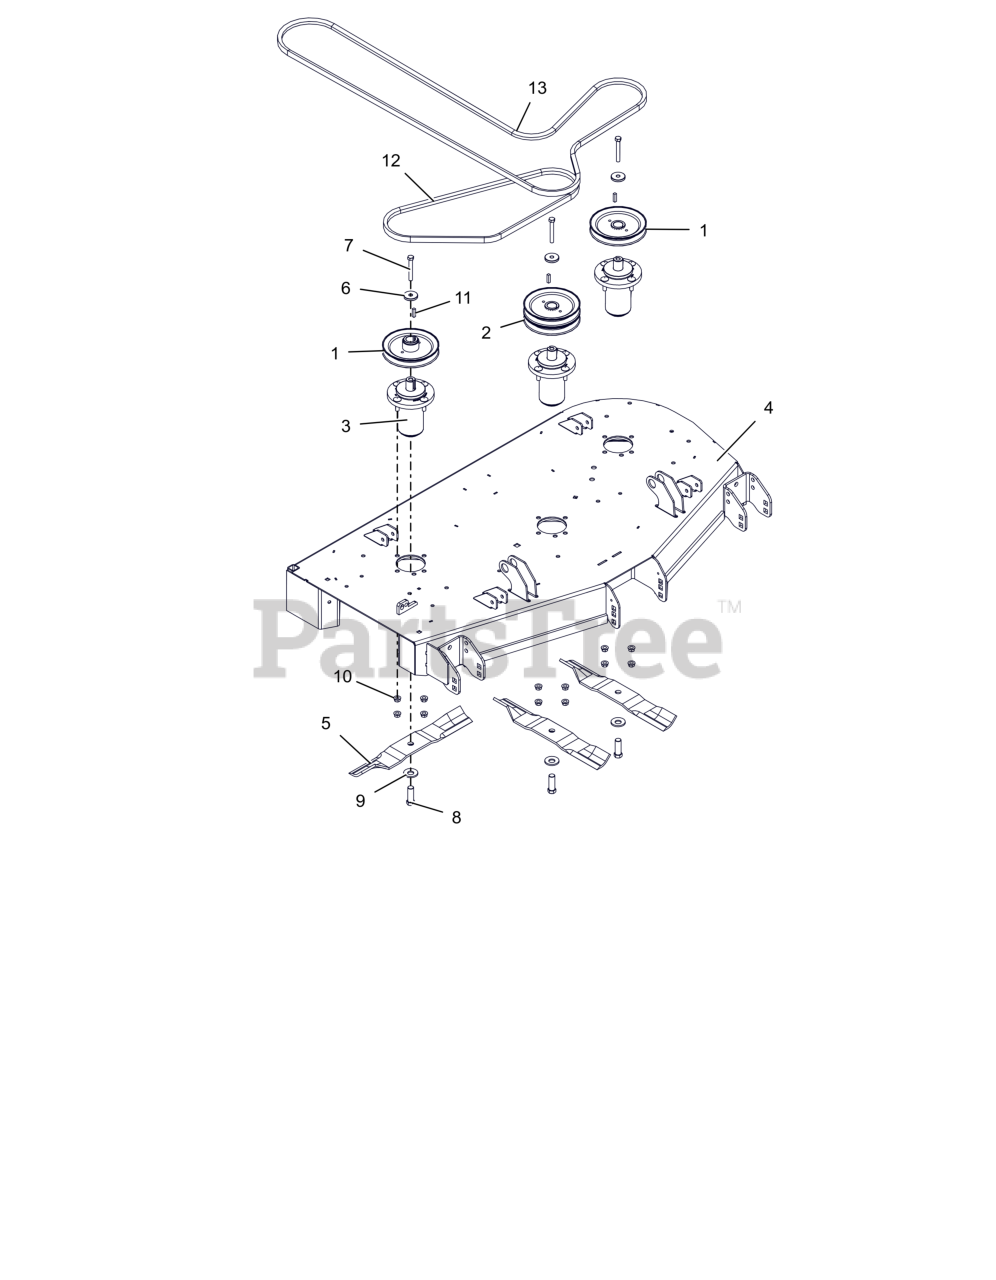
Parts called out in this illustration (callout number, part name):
1	PULLEY, SINGLE-1"ID X 6" OD
2	PULLEY, DOUBLE
3	ASM, MAINT FREE ALUM SPINDLE
4	KIT,DECK-48" W/DECALS - ARIENS
5	BLADE, 16.19" MOWER (HI-LIFT)
6	RETAINER, SHEAVE
7	BLT, HEX .38-16X2.75 G8 ZCC
8	BLT, HEX .62-18X1.75 G8 ZCC
9	WSHR-BLVL .669X1.535X.138
10	NUT-LK-CTR-FLG .375-16 GF ZCC
11	KEY, SQ .25X.25X1.00 RC 40-50
12	V-BELT, B-COGGED
13	V-BELT, HB SECTION
